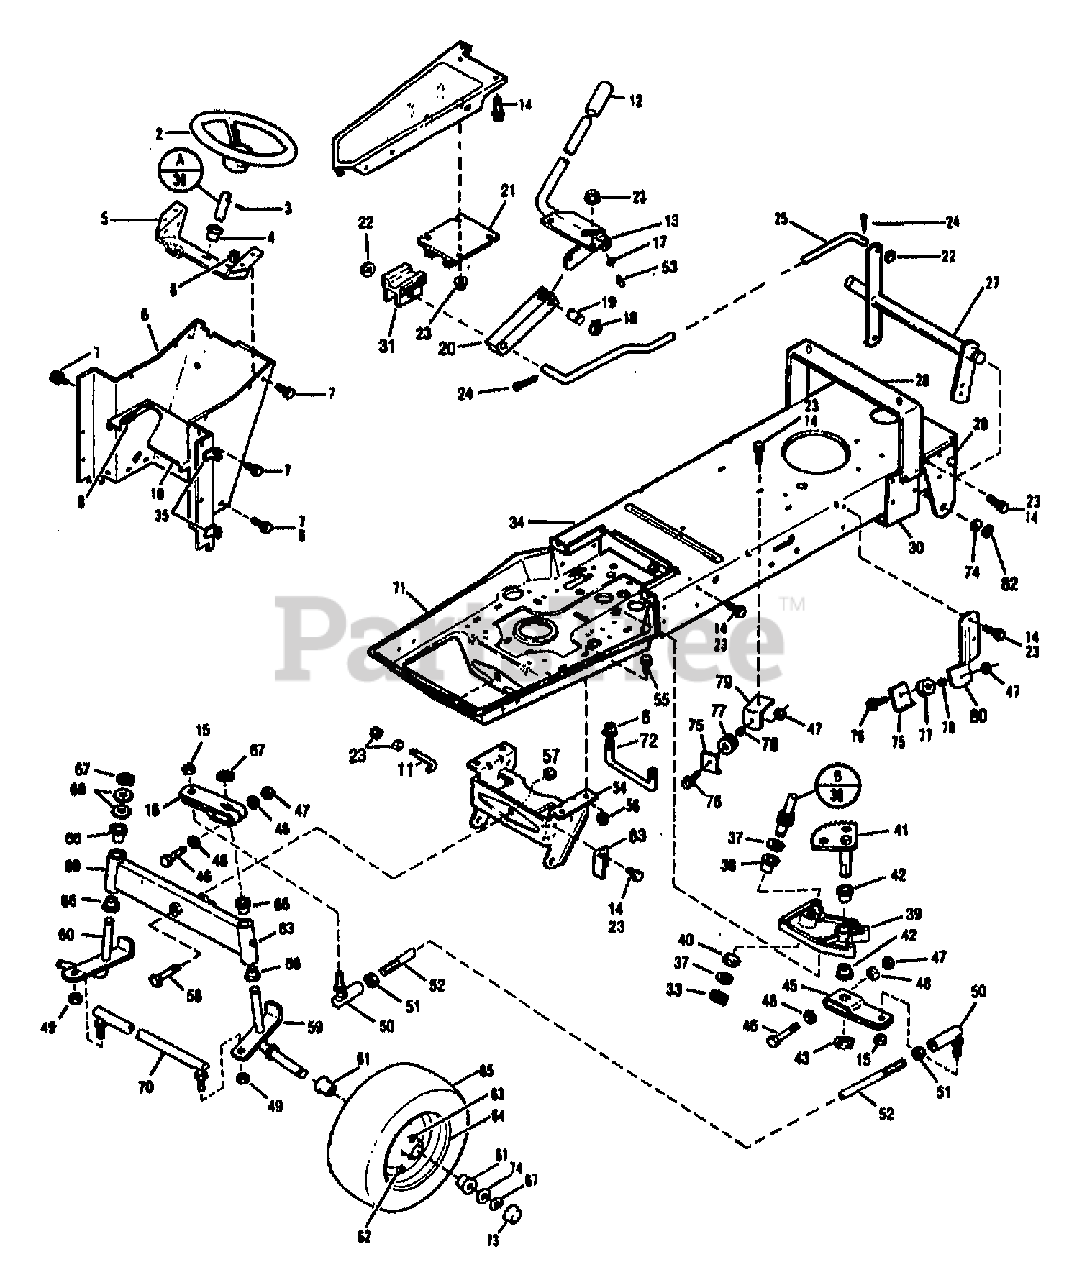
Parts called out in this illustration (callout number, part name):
2	WHEEL-STEERING {13064,13065}
2	WHEEL-STEERING {13066}
3	PIN-ROLL .25X2.25 {13064,13065}
3	PIN-DRIVE .25X1.5 {13066}
4	BEARING-FLANGED NYLON
5	SUPPORT-STEERING SHAFT
6	NUT-HF/LK 1/4-20 ZP
7	SCR-HH 1/4-20X.625
8	SUPT-INSTRUMENT PANEL {13065,13066}
8	SUPT-INSTRUMENT PANEL {13064}
9	NUT-SPEED
10	SUPPORT-BATTERY
11	GUIDE-BELT
12	GRIP-FLEX
13	ASSM-LIFT LEVER
14	SCR-LOCK
15	NUT-HEX/JAM 1/2-20 ZP
16	ASSM-ARM SPINDLE
17	WASHER
18	RING-RETAINING
20	LINK-PUSH
21	GUIDE-STAT
22	WASHER-1.06X.531X.1 ZP
23	NUT-HFLK 5/16-18 ZP
24	PIN-COTTER .120X1.00 ZP
25	ROD-LIFT
27	ASSM-LIFT SHAFT
28	ASSM-FENDER SUPPORT
29	ASSM-PANEL REAR
30	AXLE-SUPPORT
31	GUIDE-SLIDE
33	RING-RETAINING
35	NUT-SPEED
36	SHIFT-STEER
37	WASHER-SHIM
38	BEARING
39	ASSM-STEER SUPT
40	WASHER-1.115X.637X.06
41	ASSM-SECTOR GEAR
42	BEARING-FLANGE
43	RING-RETAIN EXT .707 ID
45	ARM-STEERING
46	SCR-HH 3/8-16X2.25 G5 ZP
47	NUT-LOCK 3/8-16
48	WASHER-.875X.390X.134
49	NUT-LOCK
50	JOINT-BALL
51	NUT-JAM
52	ROD-STEERING
53	FITTING-GREASE
54	BRKT-ATTACHMENT
56	NUT-HFLK 3/8-16 ZP
57	NUT-H/LK 5/8-11
58	SCR-HH 5/8-11X2.25 G5 ZP
59	ASSM-SPINDLE LH
60	ASSM-SPINDLE RH
61	BUSHING
62	STEM-VALVE
63	FITTING-GREASE 1/4-28X2.00
64	WHEEL-RED
65	TIRE 15X6.00-6RS
66	BUSHING
67	RING-RET."E".577 ID
68	WASHER-1.25X.765X.049
69	ASSM-FRONT AXLE
70	ROD-TIE
71	FRAME-FRONT
72	GUIDE-BELT
73	CAP-DUST
74	WASHER-1.38 X.765X .06 ZP
75	GUIDE-CABLE
76	SCR-HH 3/8-16X1.25
77	PULLEY-CABLE
78	SPACER-.75X.40X.51 P/M
79	BRACKET
80	BRACKET
82	RING-RET."E".577 ID
83	BRACKET
